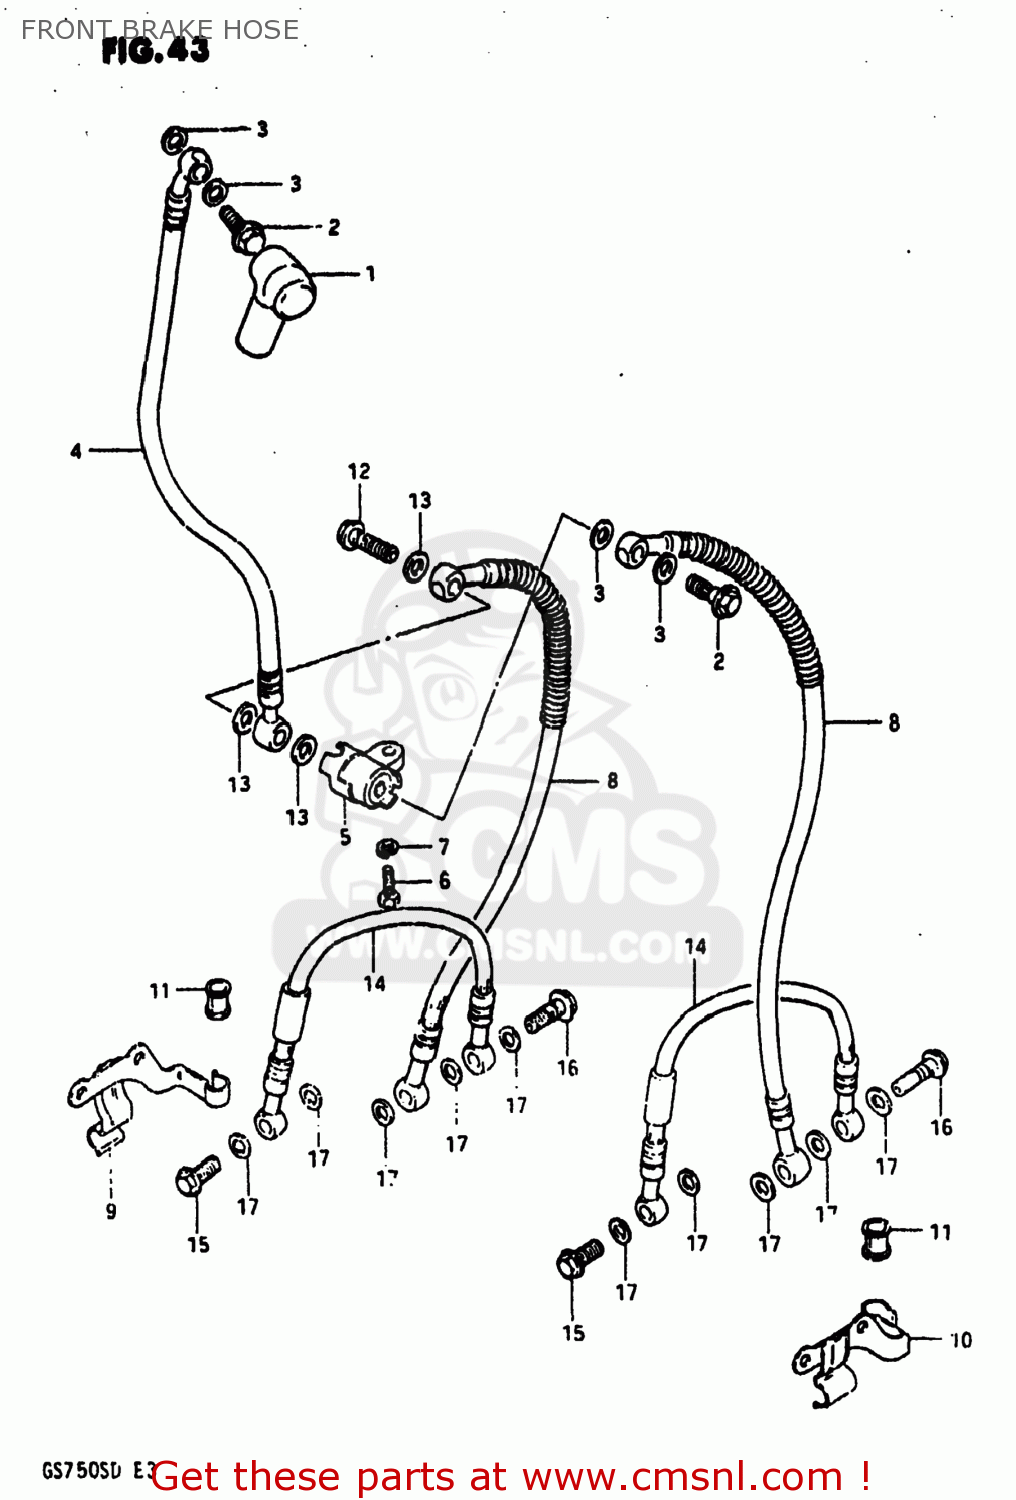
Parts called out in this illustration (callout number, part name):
2	BOLT UNION
3	WASHER
4	HOSE,BRAKE NO.1
5	JOINT,BRAKE HOSE
6	BOLT
7	LOCK WASHER
8	HOSE,FRONT BRAKE
9	CLAMP,BRAKE HOSE,RIGHT
10	CLAMP,BRAKE HOSE,LEFT
11	BUSH,BRAKE HOSE GUIDE,NO.2
12	BOLT,UNION
13	WASHER
14	HOSE,ANTI-NOSE DIVE
15	BOLT UNION
16	BOLT,UNION
17	WASHER
